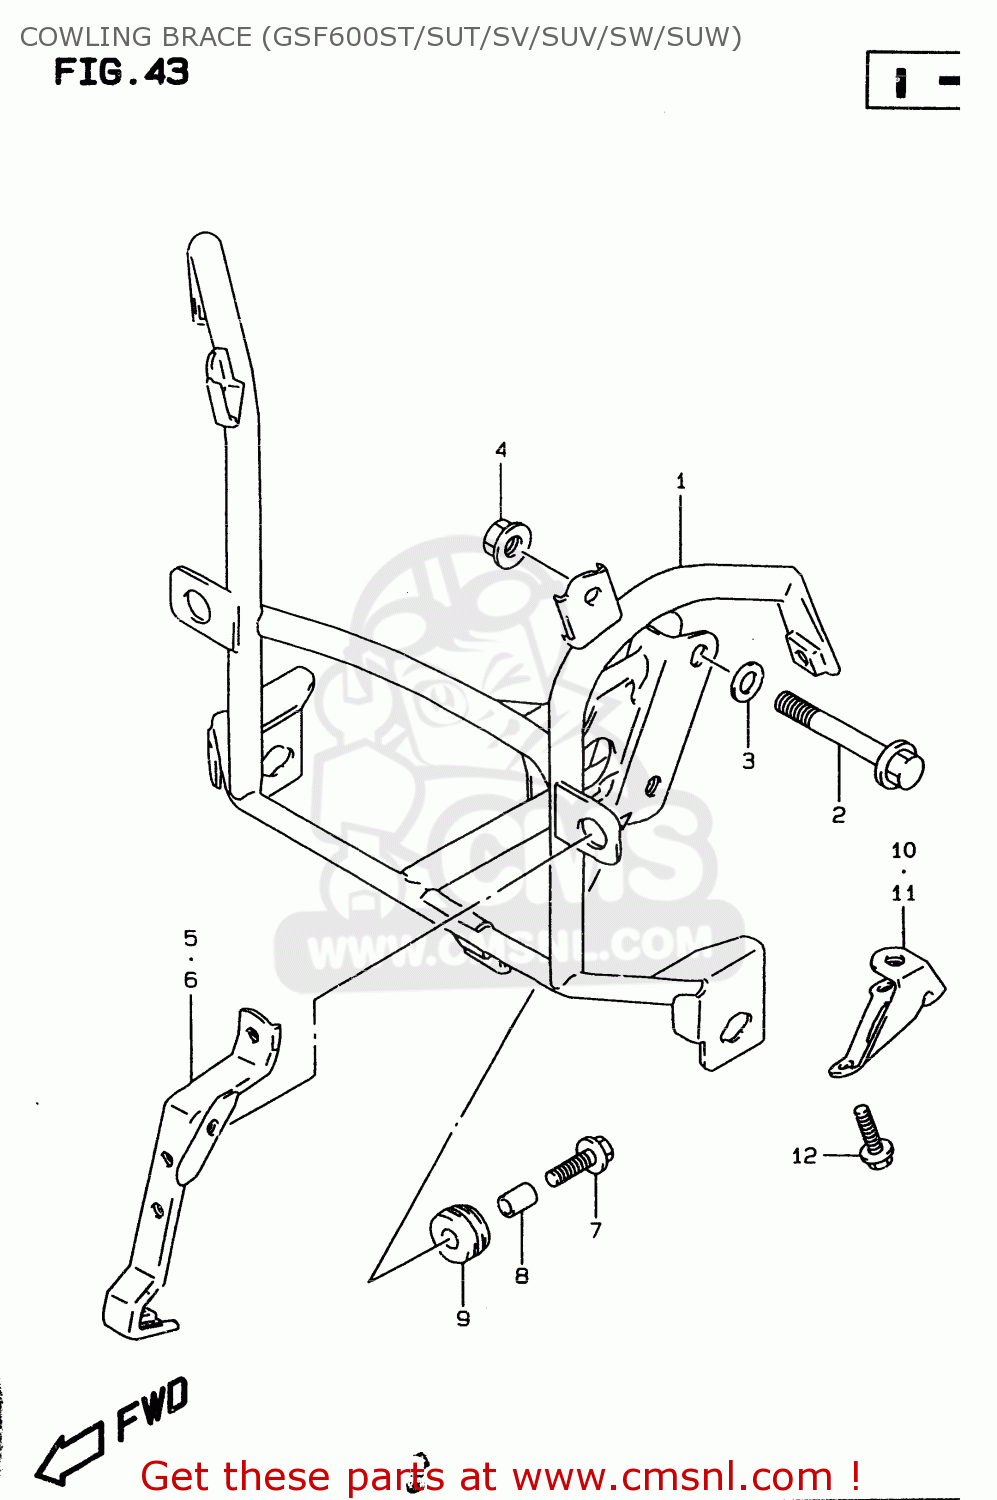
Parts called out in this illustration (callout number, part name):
1	BRACE COMP,COWLING
2	BOLT(8X40)
3	WASHER
4	NUT
5	BRACKET,HEADLAMP,R
6	BRACKET,HEADLAMP,L
7	BOLT(6X25)
8	SPACER(6.5X9X10)
9	CUSHION
10	BRACKET,COWLING RR,R
11	BRACKET,COWLING RR,L
12	BOLT
